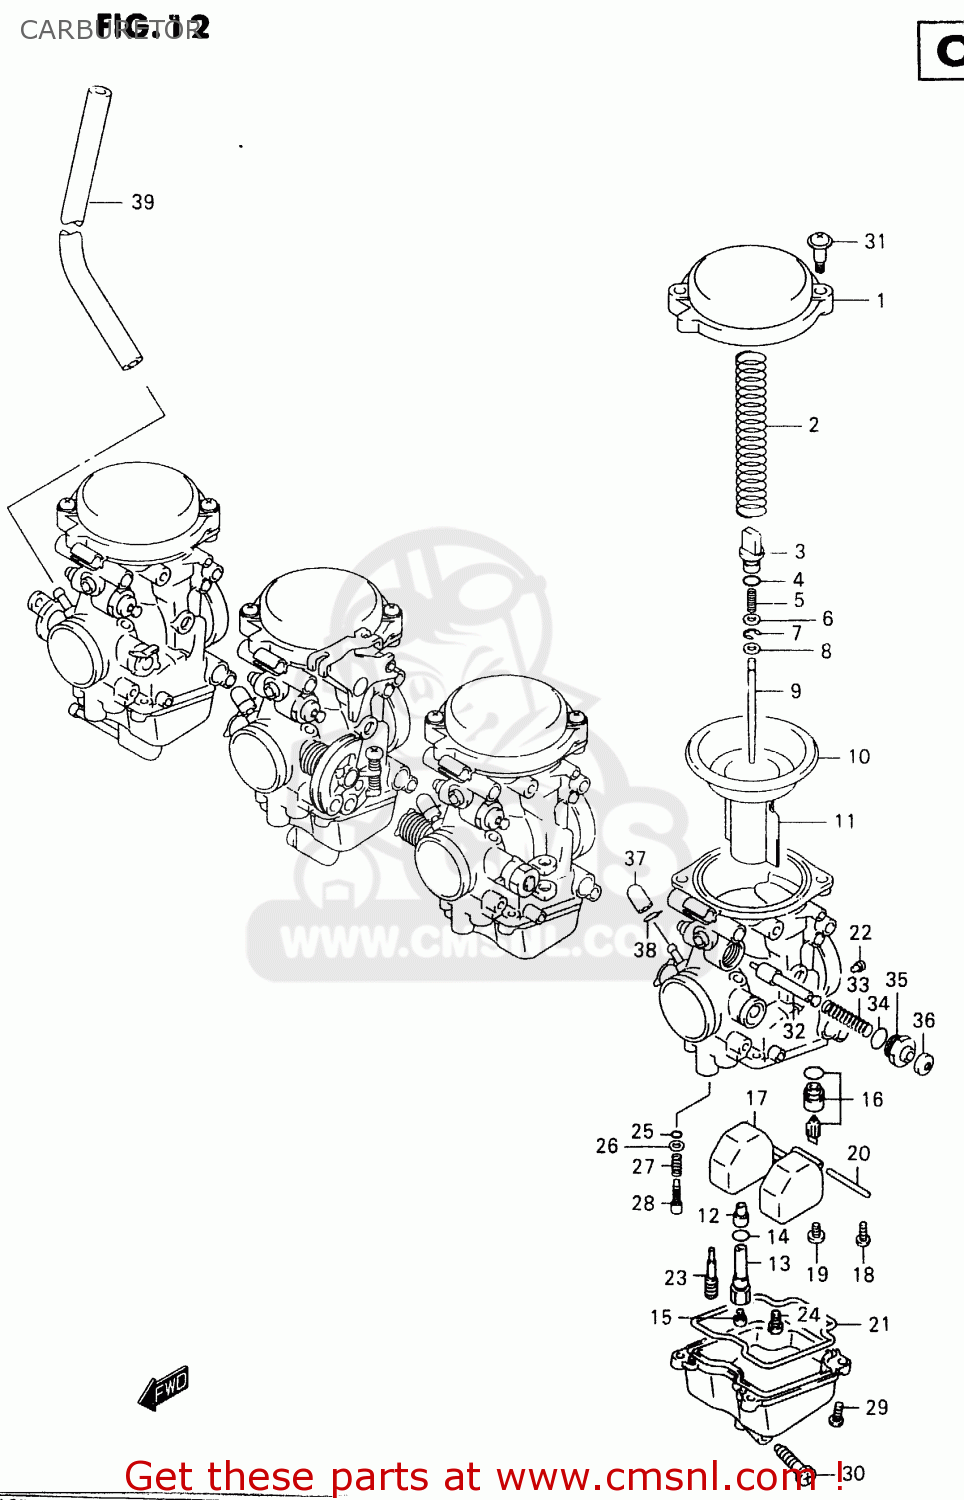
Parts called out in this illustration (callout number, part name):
1	COVER,DIAPHRAGM
2	SPRING
3	HOLDER
4	O RING(D:1.9,ID:4.8)
5	SPRING
6	WASHER
7	E RING,MULTIPLE JET NOZZLE
8	RING
9	NEEDLE,JET
10	DIAPHRAGM
11	VALVE,PISTON
12	JET,NEEDLE(P-0)
13	HOLDER,JET
14	O RING
15	JET,MAIN(115)
16	VALVE ASSEMBLY,NEEDLE
17	FLOAT ASSY
18	SCREW
19	SCREW
20	PIN,FLOAT
21	GASKET (NAS)
22	JET,POWER(145)
23	JET,PILOT(12.5)
24	JET,STARTER(50)
25	O RING,PILOT AIR SCREW
26	WASHER
27	SPRING,THROTTLE SCREW
28	ADJUSTER
29	SCREW
30	SCREW,DRAIN
31	SCREW
32	PLUNGER
33	SPRING
34	O RING
35	GUIDE SCREW,PLUNGER
36	CAP,STARTER VALVE
37	CAP
38	CLIP
39	HOSE
